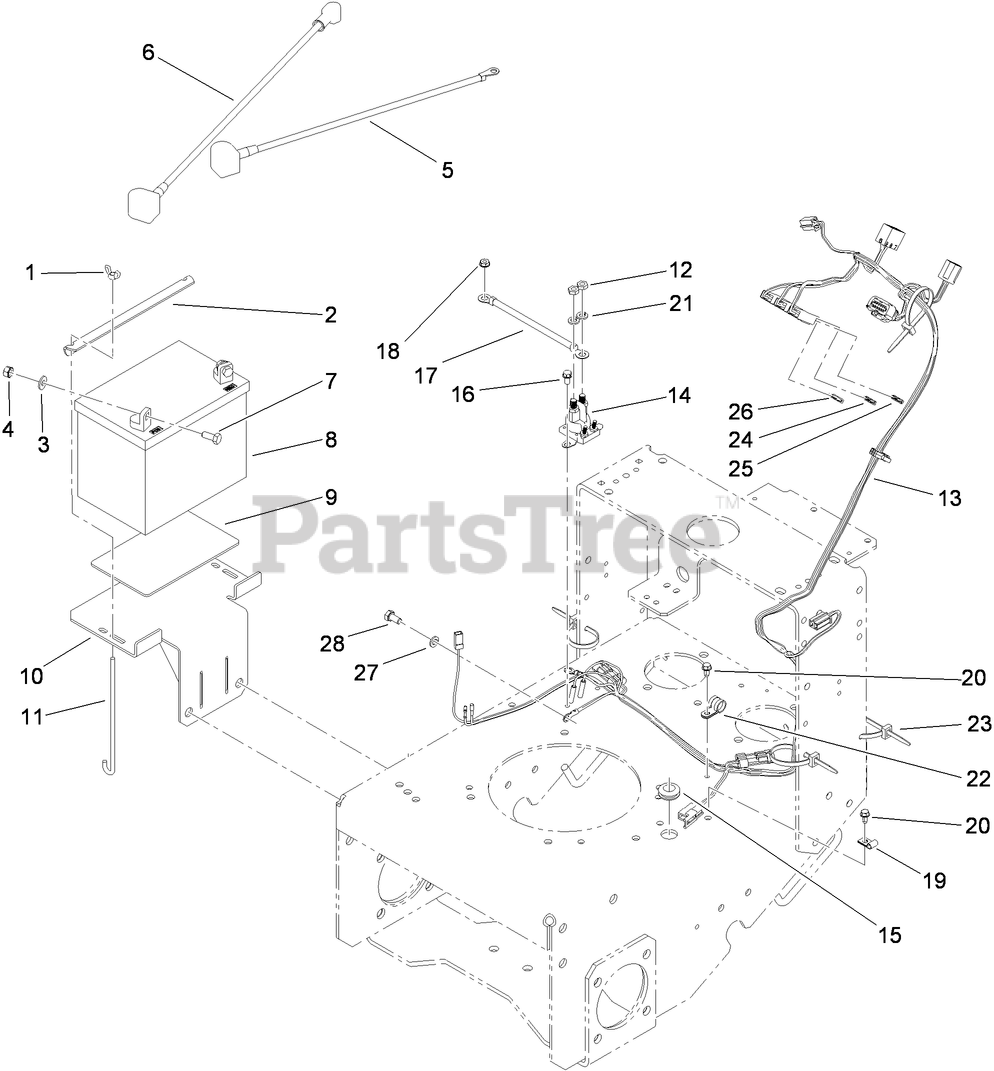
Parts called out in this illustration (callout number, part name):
1	WINGNUT
2	ANGLE-BATTERY
3	WASHER-FLAT
4	NUT-KEPS
5	CABLE-BATTERY, BLACK
6	CABLE-BATTERY, RED
7	SCREW-HH
8	BATTERY-DRY
9	PAD-SKID, ANTI
10	TRAY-BATTERY
11	BOLT-HOLDDOWN
12	NUT-JAM
13	HARNESS-WIRE, ES TWIN LEVER
14	SWITCH-SOLENOID
15	GROMMET
16	SCREW-HWH
17	CABLE-BATTERY, POS
18	NUT-KEPS
19	CLIP-CLOSED, INSULATED
20	SCREW
21	WASHER-LOCK
22	CLAMP-R
23	TIE-CABLE
24	FUSE-BLADE, 25 AMP
25	FUSE-BLADE, 30 AMP
26	FUSE-BLADE, 10 AMP
27	WASHER-LOCK
28	SCREW-HH
